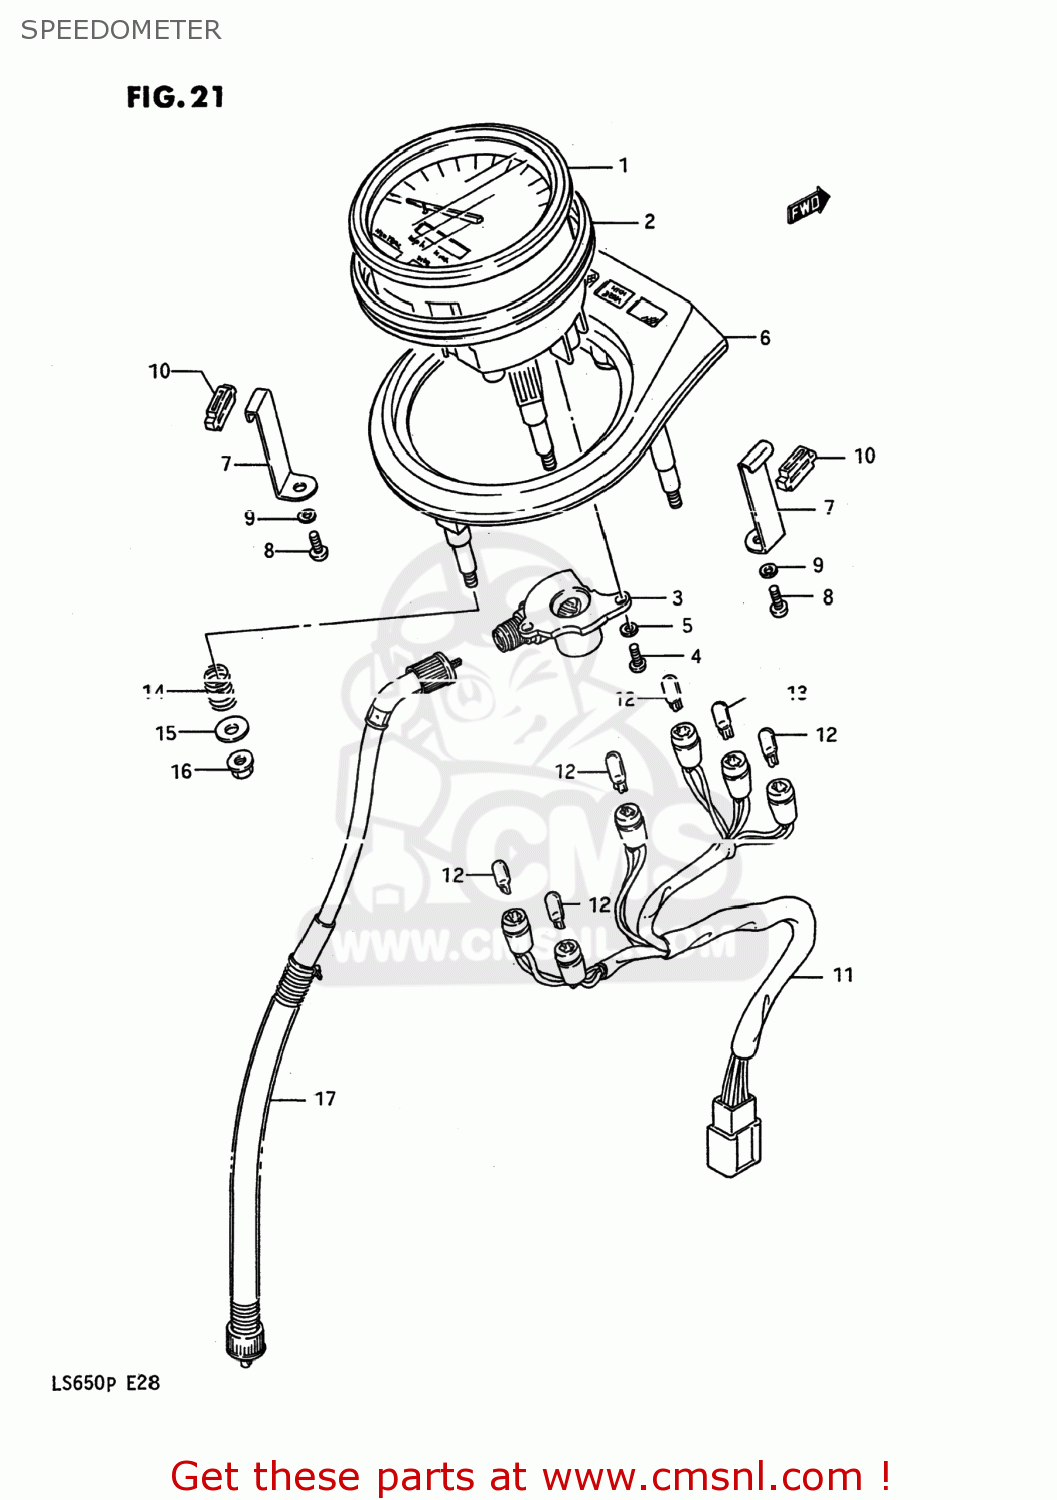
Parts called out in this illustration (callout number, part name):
1	SPEEDOMETER(KILO)
2	CUSHION,METER
3	GEAR BOX,SPEEDOMETER
4	SCREW
5	WASHER,LOCK 4M
6	HOOD,METER
7	BRACKET,METER
8	SCREW
9	WASHER,LOCK 4M
10	CUSHION
11	SOCKET,METER
12	BULB(12V3W,T6.5)
13	BULB(12V1.7W,T6.5)
14	SPRING
15	WASHER (5.5X14X1.2)
16	NUT
17	CABLE ASSY,SPEEDOMETER
